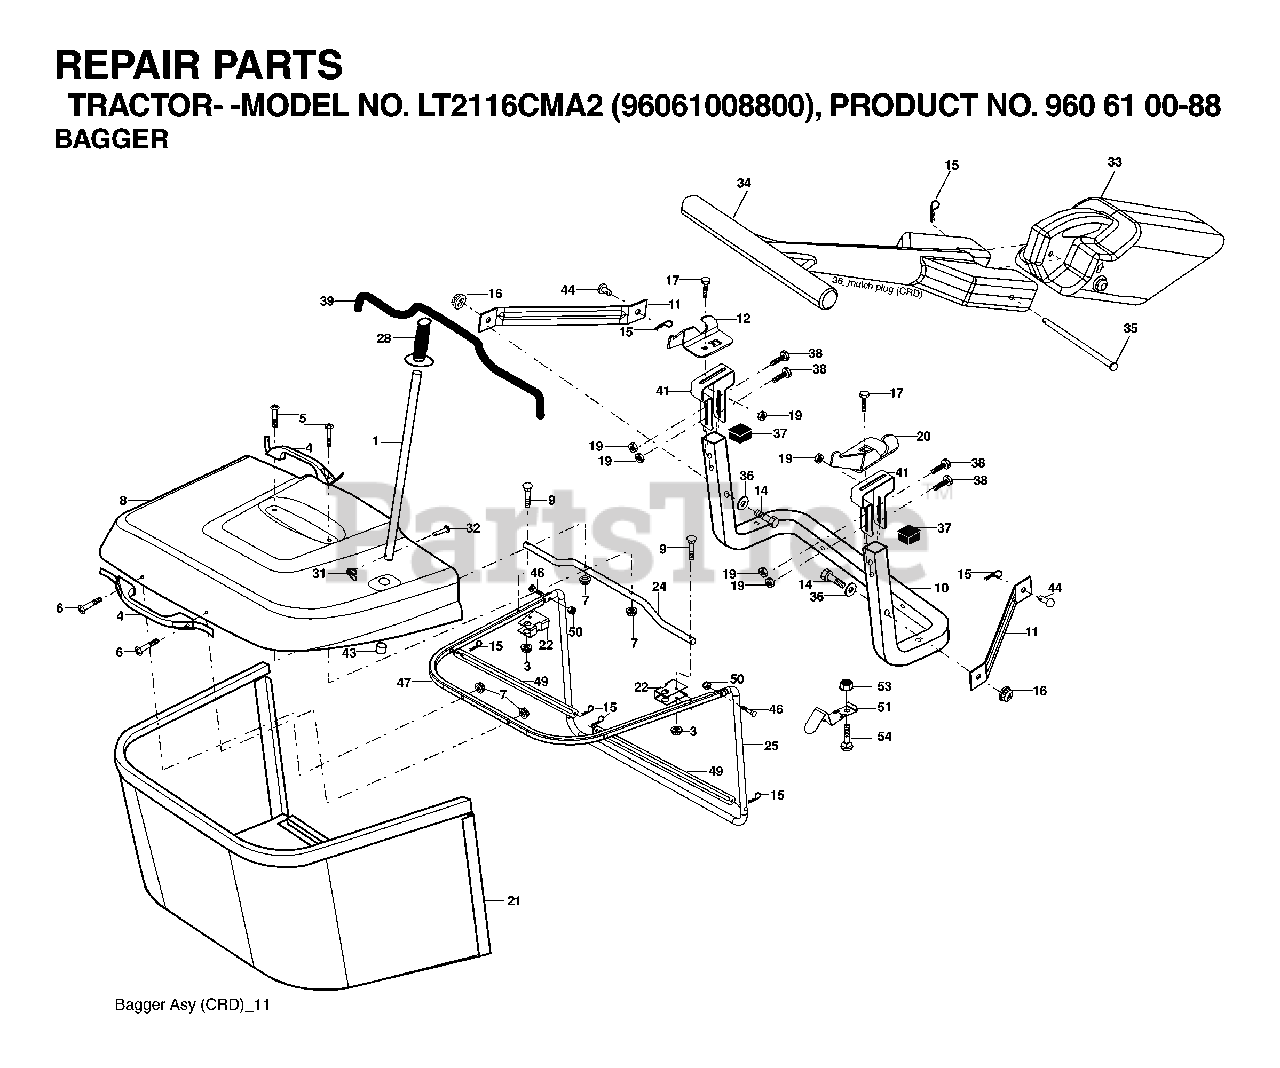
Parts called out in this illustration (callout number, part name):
1	TUBE HANDLE
3	NUT T
5	SCREW.PAN.HEAD
11	BRACKET
14	BOLT-HEX EAK
15	RETAINER-SPRNG RB
16	NUT LOCK FLG 3/8-16 UNC
17	BOLT
19	NUT LOCK HEX FLANGE 5/16-18
20	BRKT.PIVOT.RH.CRD
22	BRACKET
24	TUBE
28	GRIP.HANDLE.BLACK
31	RETAINER CLIP
32	RIVET,DRILLED
33	PLUG
35	PIN
38	BOLT.5/16-18X2.5
41	BRKT, BAGGER
43	PLUG, TUBING END
46	BOLT.CARRIAGE.5/16-18
50	NUT.71038.31-18.HEX.NYLOCK
53	NUT
54	BOLT
